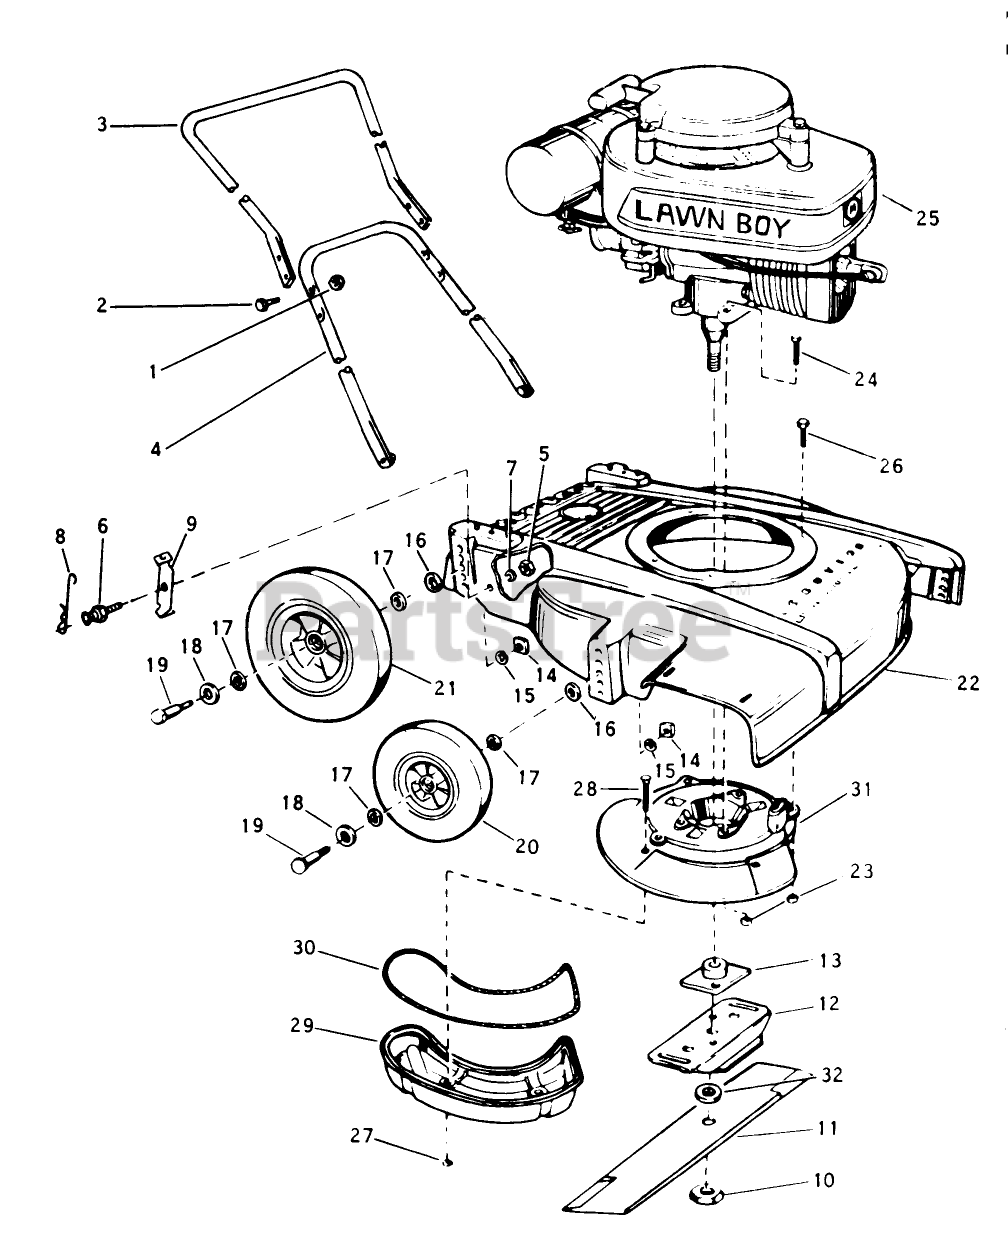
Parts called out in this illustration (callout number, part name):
7	Lockwasher
10	NUT-BLADE
13	PLATE AND COLLAR ASM
15	WASHER, LOCK
16	WASHER WROUGHT
27	LOCKNUT E
